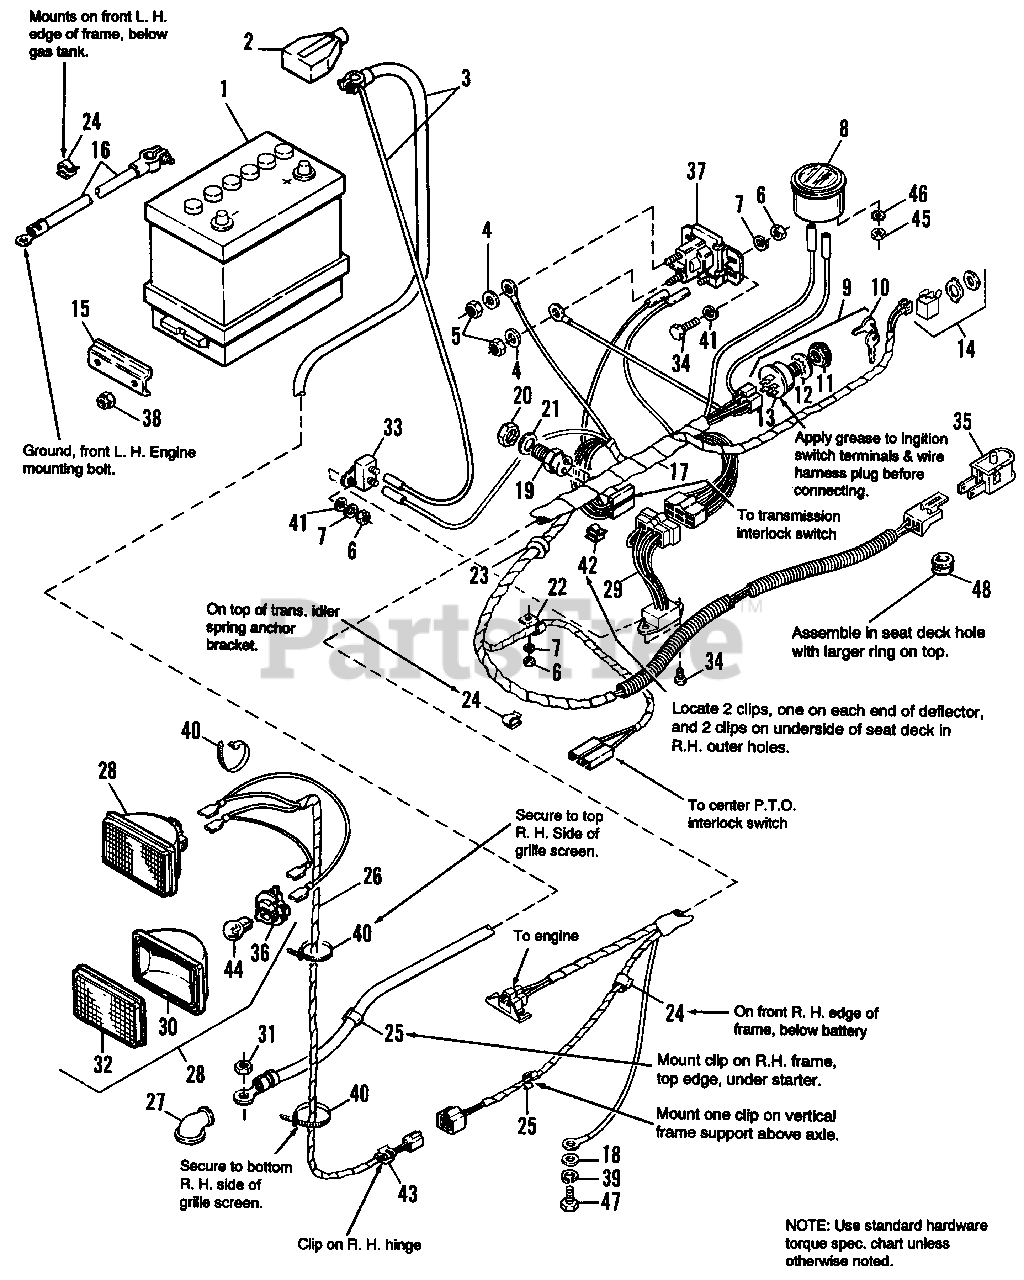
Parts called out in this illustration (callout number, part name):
2	INSULATING CABLE BOOT
3	CABLE (Battery to Solenoid)
4	LOCKWASHER, 5/16
5	NUT, Hex, 5/16-24
6	NUT, Hex, Full, 1/4-20
7	LOCKWASHER, 1/4
9	IGNITION SWITCH KIT (Mfg. Nos. 1692143, 1692144, See Note below) (Incl. Ref. Nos. 10, 11, 12 & 13)
10	KEY SET (2)
11	NUT, Adaptor
12	LOCKWASHER, Int., 5/8
14	SWITCH, Toggle
16	CABLE (Battery to Ground)
17	HARNESS ASSY.
18	WASHER, 15/32
19	SWITCH, Interlock
21	WASHER, 9/16
22	CLIP, Cable
24	CLIP, Tinnerman
25	CLIP, Tinnerman
27	COVER, Terminal
28	HEADLIGHT ASSY. (Incl. Ref. Nos. 30, 32, 36 & 44)
29	MODULE, Interlock
30	REFLECTOR, Housing
31	NUT, Hex, Flange Hd., M8-125
32	LENS, Clear
33	BREAKER, Circuit
34	CAPSCREW, Hex Hd., 1/4-20 x 3/4
35	SWITCH, Seat
36	SOCKET, Bulb
37	SOLENOID, Starter
38	NUT, Elastic, 5/16-18
39	LOCKWASHER, 7/16
41	WASHER, Special, 1/4
42	CLIP, Wire
43	CLIP, Speed Cable
45	NUT, Hex, #10-32
46	LOCKWASHER, Ext. Tooth
47	CAPSCREW, Hex Hd., 7/16-14 x 1
48	BUSHING, Snap
